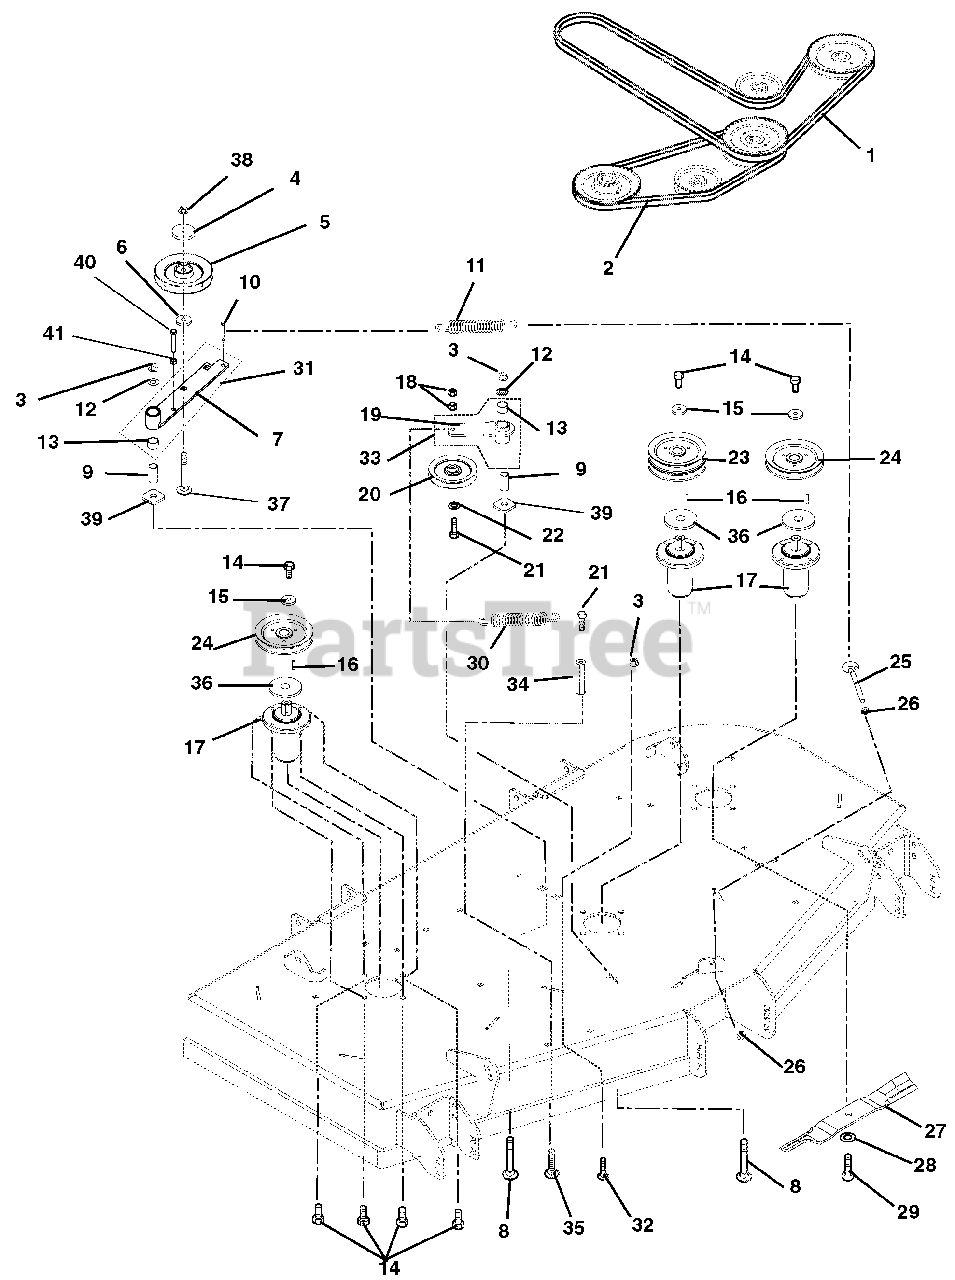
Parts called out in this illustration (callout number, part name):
1	Belt, 175" Long, PTO Drive Hex (992322)
2	V-Belt, 56" Long Cog B-Section (992322)
3	Nut, .50-13 Nyloc Flange
4	Cap, Idler Bearing Sealing
5	Pulley, V 6.0 x .500 ID SNGL. Bearing
6	Bushing, Spacer .502 x .997 x .50
7	Weldment, Idler Arm
8	Bolt, Round Head Square Neck .50-13 x 3.50
9	Bushing, Spacer .505/.500 x .999/.996 x 2.05/2.03
10	Bolt, Shoulder EP .38-16 x .30 Hex
11	Spring, Extension (Deck Idler)
12	Washer, Flat Steel .531x 1.250 x.100
13	Bushing, 1.00 x 1.125 x 1.936
14	Bolt, Hex .38-16 x 1.00
15	Washer, Flat Steel .406 x 1.50 x .245
16	Key, Square .25 x .25 x 1 RC 40-50
17	Spindle Assembly
18	Nut, Locking-Center .38-16
19	Weldment, Idler Arm
20	Assembly, V-Idler 5.00 O.D.
21	Bolt, Hex .38-16 x 2.25
22	Washer, Flat Steel .406 x .812 x .065
23	Sheave, Double 1" ID x 6.00" OD (992322)
24	Sheave, Single 1" ID x 6.00" OD (992322)
25	Bolt, .38-16 x 4.50 .62 Diameter Eye
26	Nut, Hex, Jam .375-16
27	Blade, 18.00" Mower, Mulch (992322)
28	Washer, Bellville .63 x 1.625 x.14
29	Bolt, Hex .62-18 x 1.75 Grade 8
30	Spring, Extension
31	Assembly, PTO Idler Pivot Arm (Includes item # 7 and item # 13)
32	Bolt, Round Head Square Neck .50-13 x 1.5, Full Thread, Grade 5
33	Assembly, Idler Pivot Arm (Includes item # 13 and item # 19 )
34	Nut, Coupling .375-16 x 1.75
35	Bolt, Round Head Square Neck .38-16 x 1.00
36	Retainer, Grease
37	Bolt, Round Head Square Neck .50-13 x 3.00 Grade 5
38	Nut, .50-13 Nyloc Flange
39	Washer, Flat .640 x 1.75 x .250
40	Bolt, Hex .38-16 x 2.75 Grade 5
41	Nut, Hex .38-16
